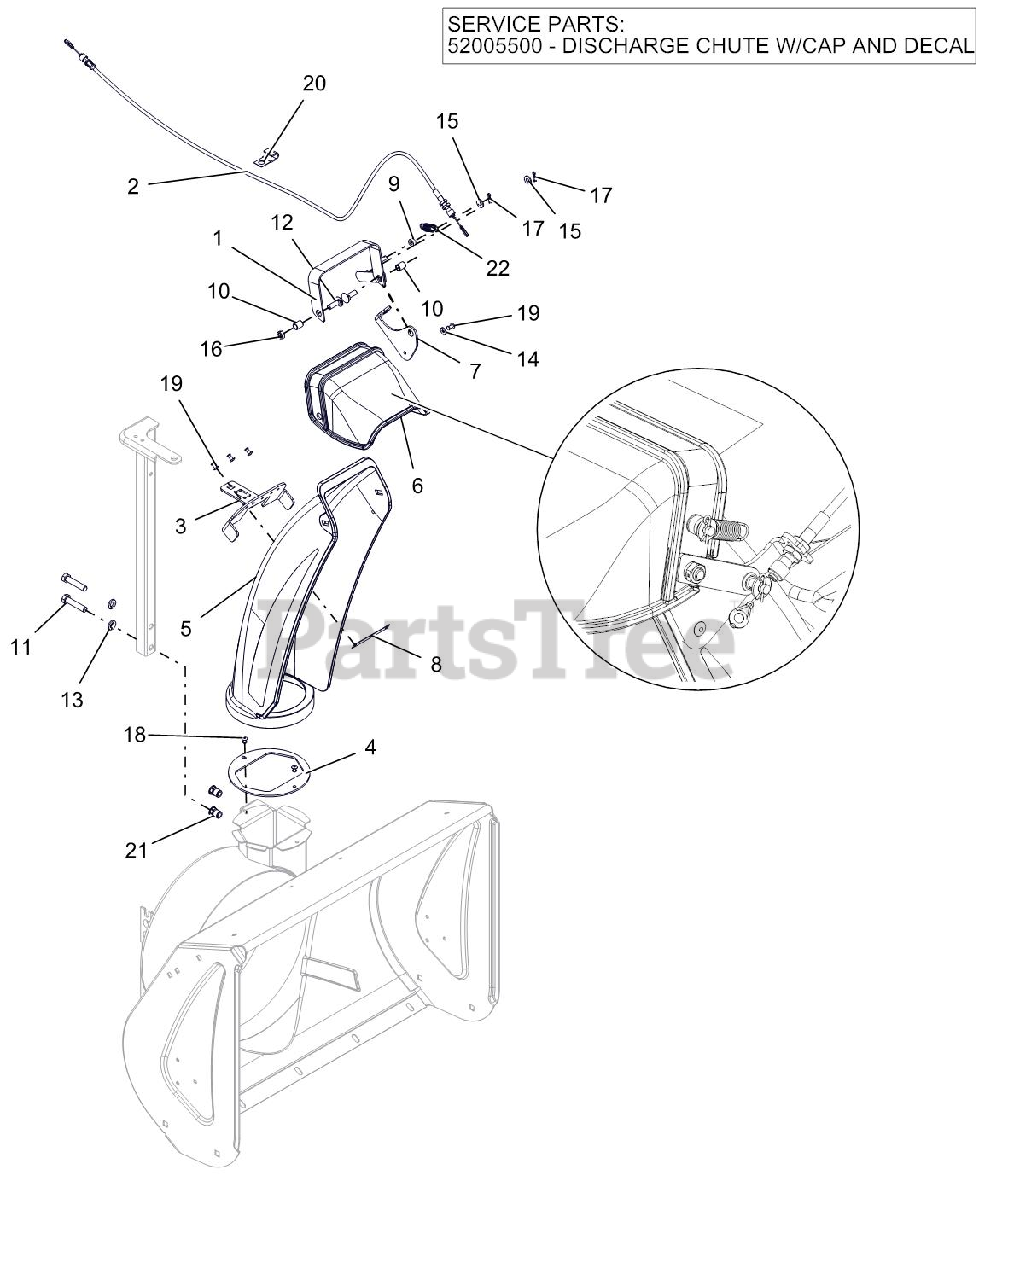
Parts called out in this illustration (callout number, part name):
1	WELDMENT, DEFLECTOR CAP SNOTEK
2	CABLE, DEFLECTOR CAP SNO-TEK
3	CHUTE MOUNT BRACKET
4	BAFFLE, COMPACT DISCHARGE
5	CHUTE, PLASTIC DISCHARGE LONG
6	CAP,PLASTIC - SNOTEK (W/DECAL)
7	BRACKET, CABLE ANCHOR SNOTEK
8	PLATE,CHUTE MOUNT BACKING
9	BSHG-SLV .265X.500X.219
10	BSHG-SLV .330X.455X.550
11	@BLT-HEX .38-16X1.75 GR5 YWZC
12	BLT,RNHDRECSHNK .31-18X1.00
13	@WSHR-LK .38X.094 REG YWZC
14	WSHR-FL-STL .196X.500X.06 YZ
15	@WSHR-FL-STL.281X.62X.065 YWZC
16	@NUT-LK-CTR-JAM .31-18 YWZC
17	PIN-HAIR INT .06X.18X.77
18	RVT-POP .187 YZ
19	RIVET, #66 STEEL POP PD BLACK
20	J-CLAMP
21	NUT, THREADED INSERT .38-16
22	SPRG, TENSION .052X.520X1.74
23	CHUTE, REMOTE DISCHARGE W/CAP
